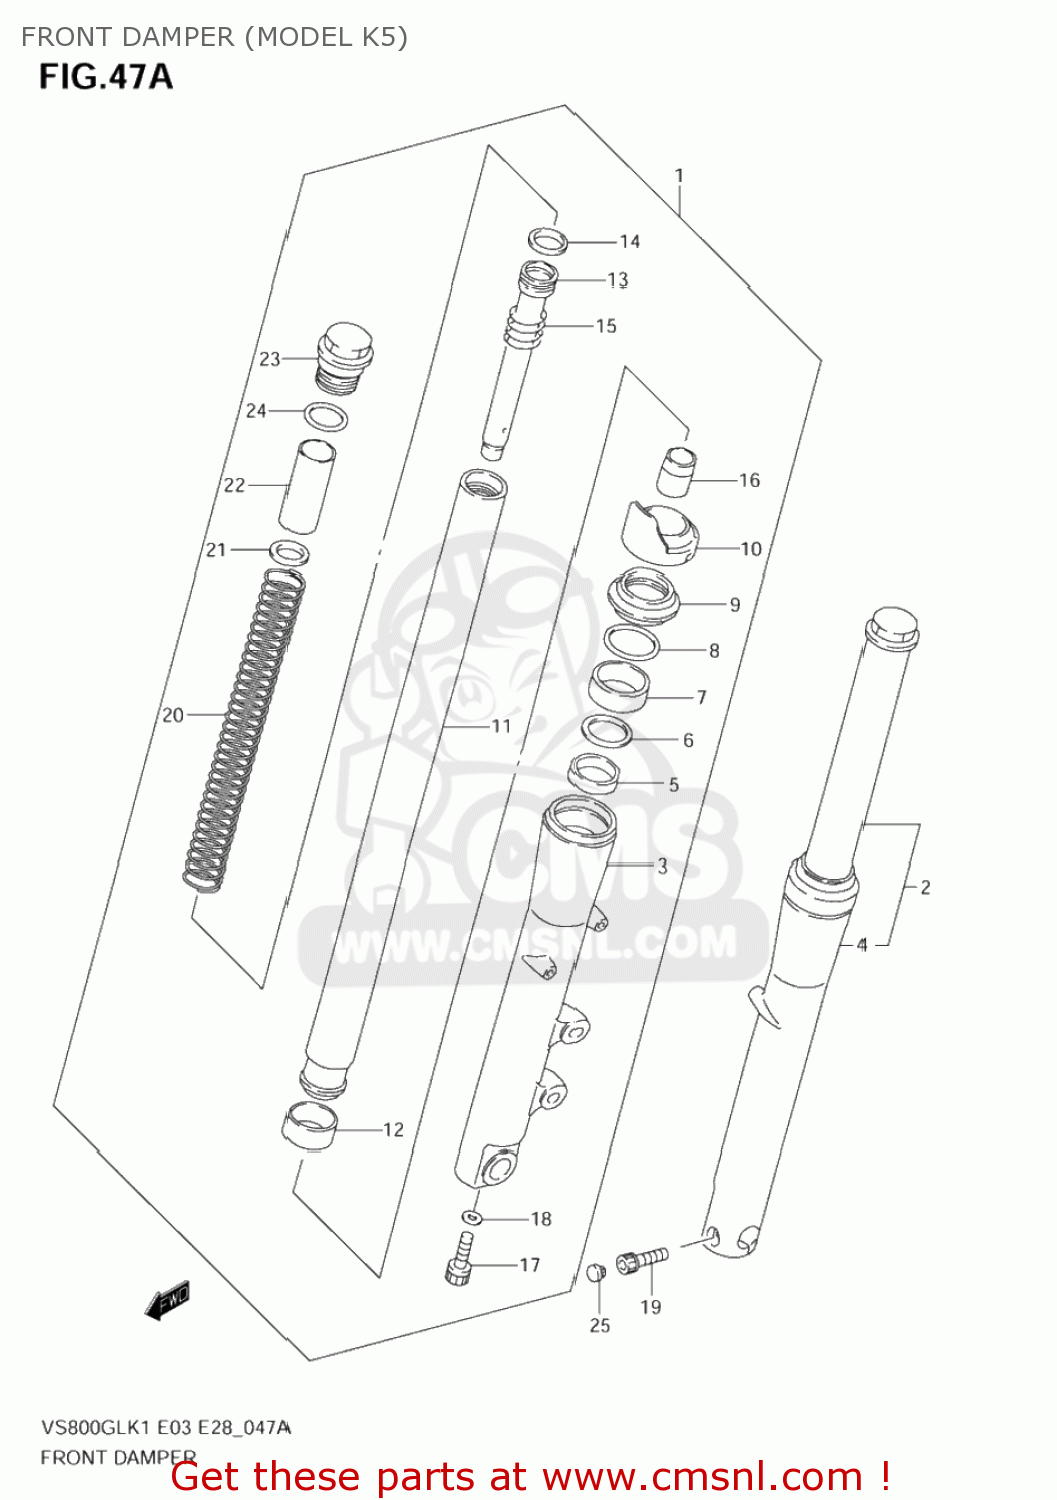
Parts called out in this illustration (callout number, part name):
1	DAMPER ASSY,FR FORK,R
2	DAMPER ASSY,FR FORK,L
3	TUBE,OUTER,R
4	TUBE,OUTER,L
5	BUSH,GUIDE
6	SPACER,SEAL
7	SEAL,OIL
8	RING,OIL SEAL STOPPER
9	SEAL,DUST
10	COVER,UPR,R
11	TUBE,INNER
12	BUSH,SLIDE
13	PIPE,SEAT
14	RING,PISTON
15	SPRING,REBOUND
16	PIECE,OIL LOCK
17	BOLT(8X27)
18	GASKET (NAS)
19	SPRING
20	WASHER,SPRING
21	COLLAR,SPRING
22	BOLT,FORK
23	O RING
24	BOLT
25	CAP(OD:14.5)
